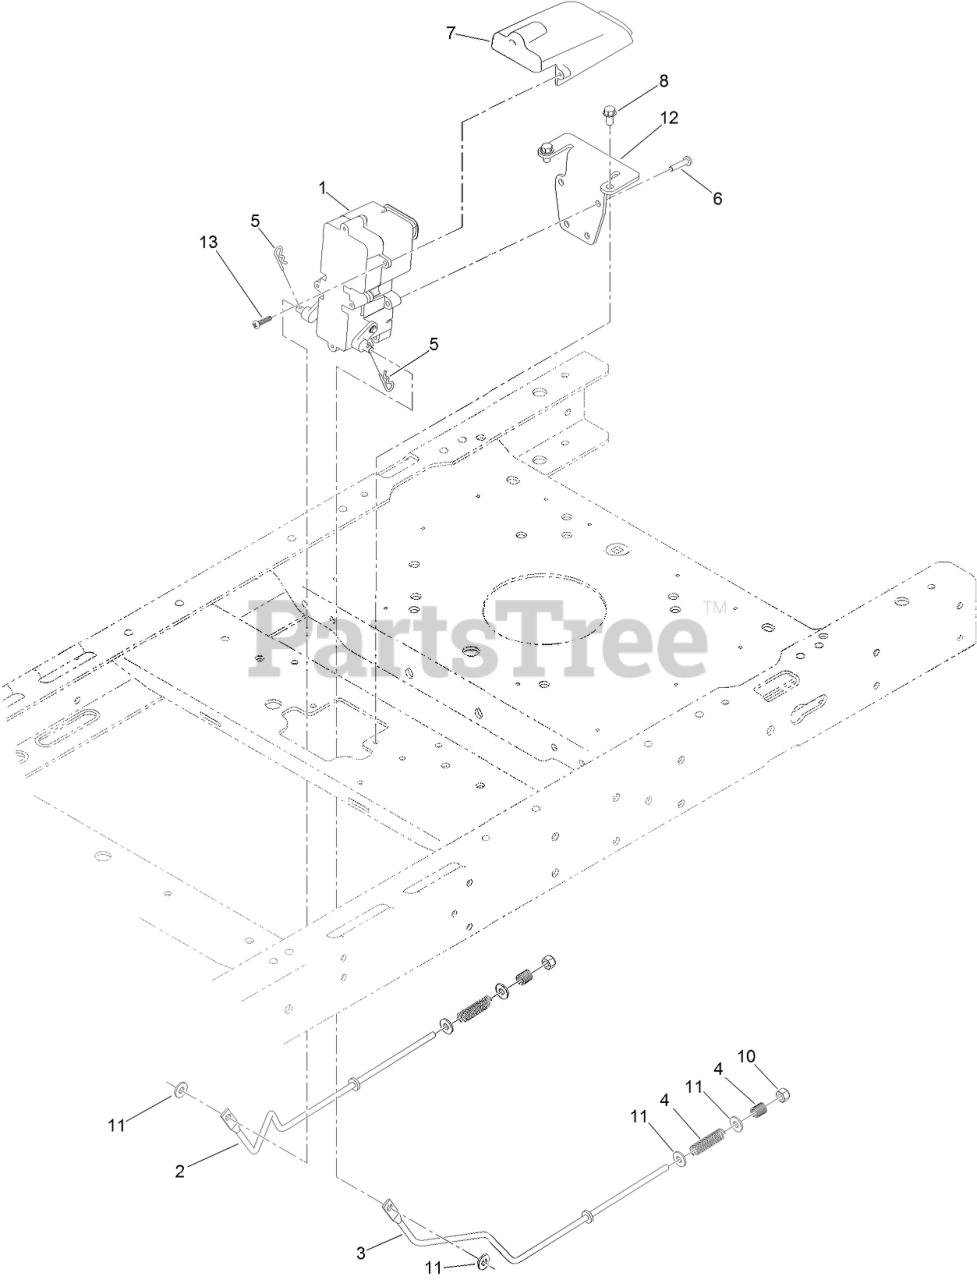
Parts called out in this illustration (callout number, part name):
1	BRAKE BOX ASM
2	ROD-BRAKE, RH
3	ROD-BRAKE, LH
4	SPRING-COMPRESSION
5	PIN-COTTER
6	SCREW-PPH
7	COVER-CONNECTOR
8	SCREW-HWH
10	NUT-LOCK, NI
11	WASHER
12	BRACKET-MOUNT, BRAKE
13	SCREW-PPH
